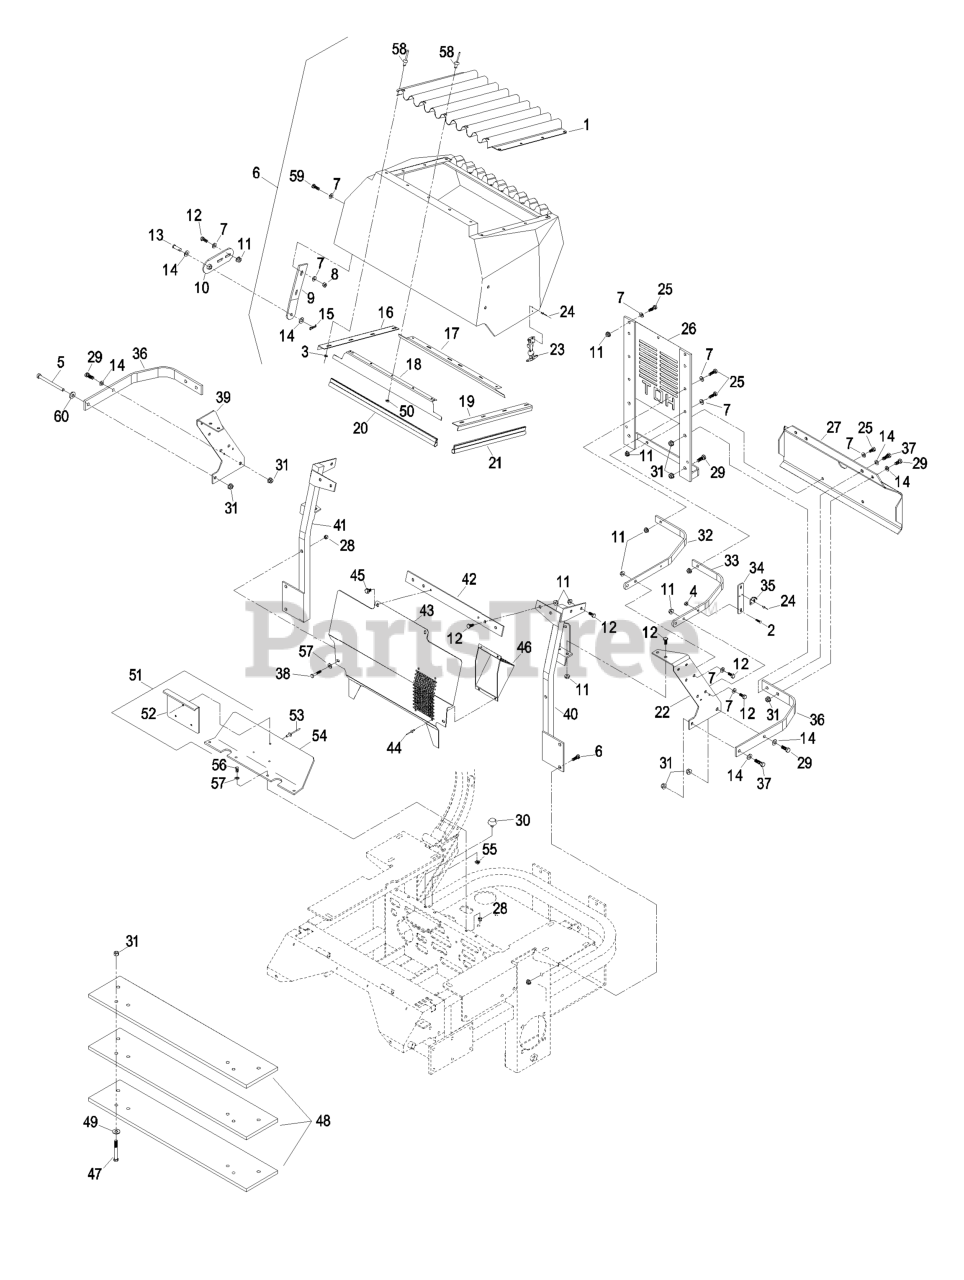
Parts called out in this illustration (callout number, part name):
1	SCREEN-RADIATOR
2	SCREW-HEAD, TRUSS
3	WASHER-FLAT
4	NUT-LOCK, NI
5	SCREW-HH
7	WASHER-PLAIN
8	NUT-LOCK, NI
9	PLATE-HINGE, HOOD
10	SHACKLE-HINGE
12	SCREW-HH
13	PIN-CLEVIS
14	WASHER-FLAT
15	PIN-COTTER
16	ANGLE-RADIATOR, RH
17	ANGLE-RADIATOR, BOTTOM
18	ANGLE-RADIATOR, TOP
19	ANGLE-RADIATOR, LH
20	SEAL-TRIM
21	SEAL-TRIM
22	PLATE-SIDE, LH
23	LATCH-RUBBER
25	SCREW-HH
28	NUT-LOCK, NI
29	SCREW-HH
31	NUT-HHF, WHIZ
34	BAR-HOOK, LATCH
37	SCREW-HH
38	SCREW-HH
39	PLATE-SIDE, RH
40	BRACE-RADIATOR, LH
43	DEFLECTOR-AIR
44	RIVET-POP
45	SCREW-HWHTF
46	PLENUM-INTAKE, AIR
47	SCREW-CARR
48	BAR,WEIGHT 38.1#
49	WASHER-BELLEVILLE
50	WASHER-SPRING
53	RIVET-POP
54	SHIELD-ENGINE
56	SCREW-HH
57	WASHER-FLAT
59	SCREW-HH
60	WASHER-BELLEVILLE
